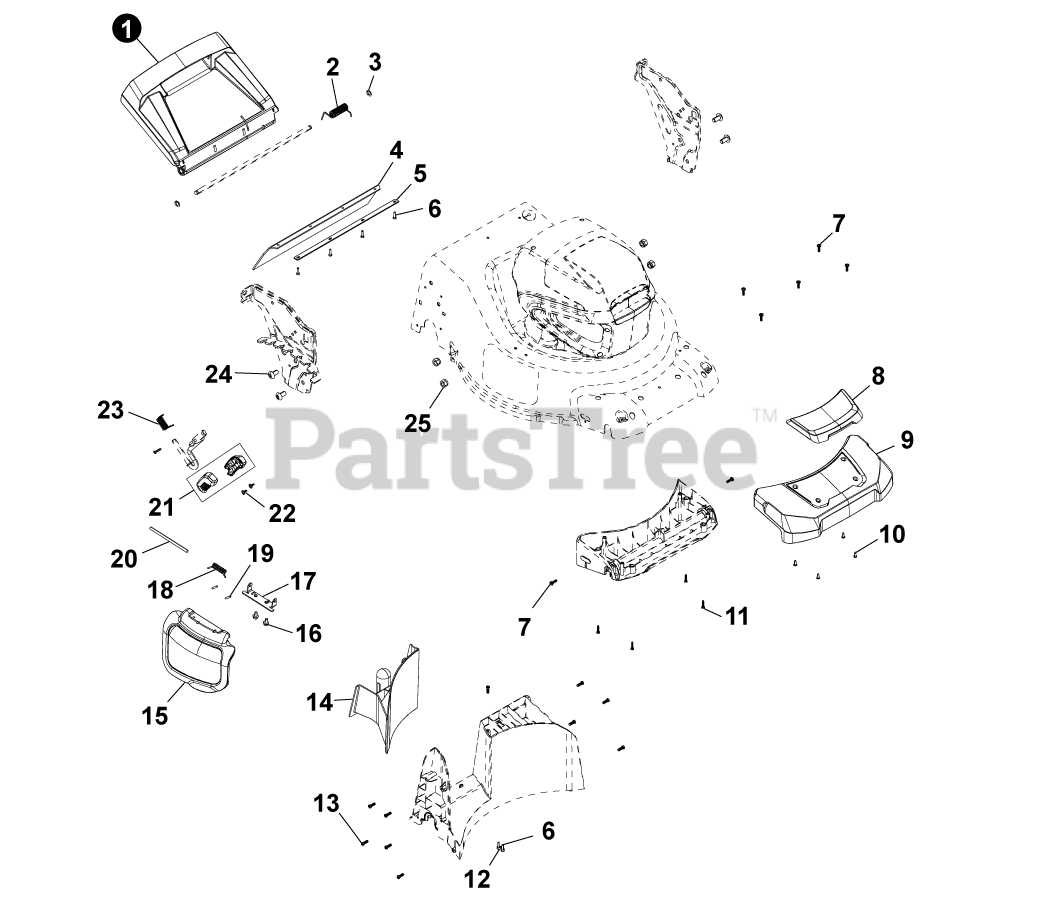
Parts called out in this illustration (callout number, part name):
1	DOOR, REAR
2	SPRING, TORSION
4	SHIELD, DEBRIS
5	PLATE, RETAINER
8	COVER, DECORATIVE
9	COVER, FRONT
12	RETAINER
14	PLUG, MULCH
15	COVER, SIDE DISCHARGE
16	BOLT, FLANGE
17	BRACKET, SIDE DISCHARGE
18	SPRING, TORSION
19	SLEEVE, RUBBER
20	SHAFT, SIDE DISCHARGE
21	HANDLE, HEIGHT ADJUSTMENT
22	SCREW, PAN HEAD SELF TAP
23	SPRING, TORSION
25	NUT, NYLOC
